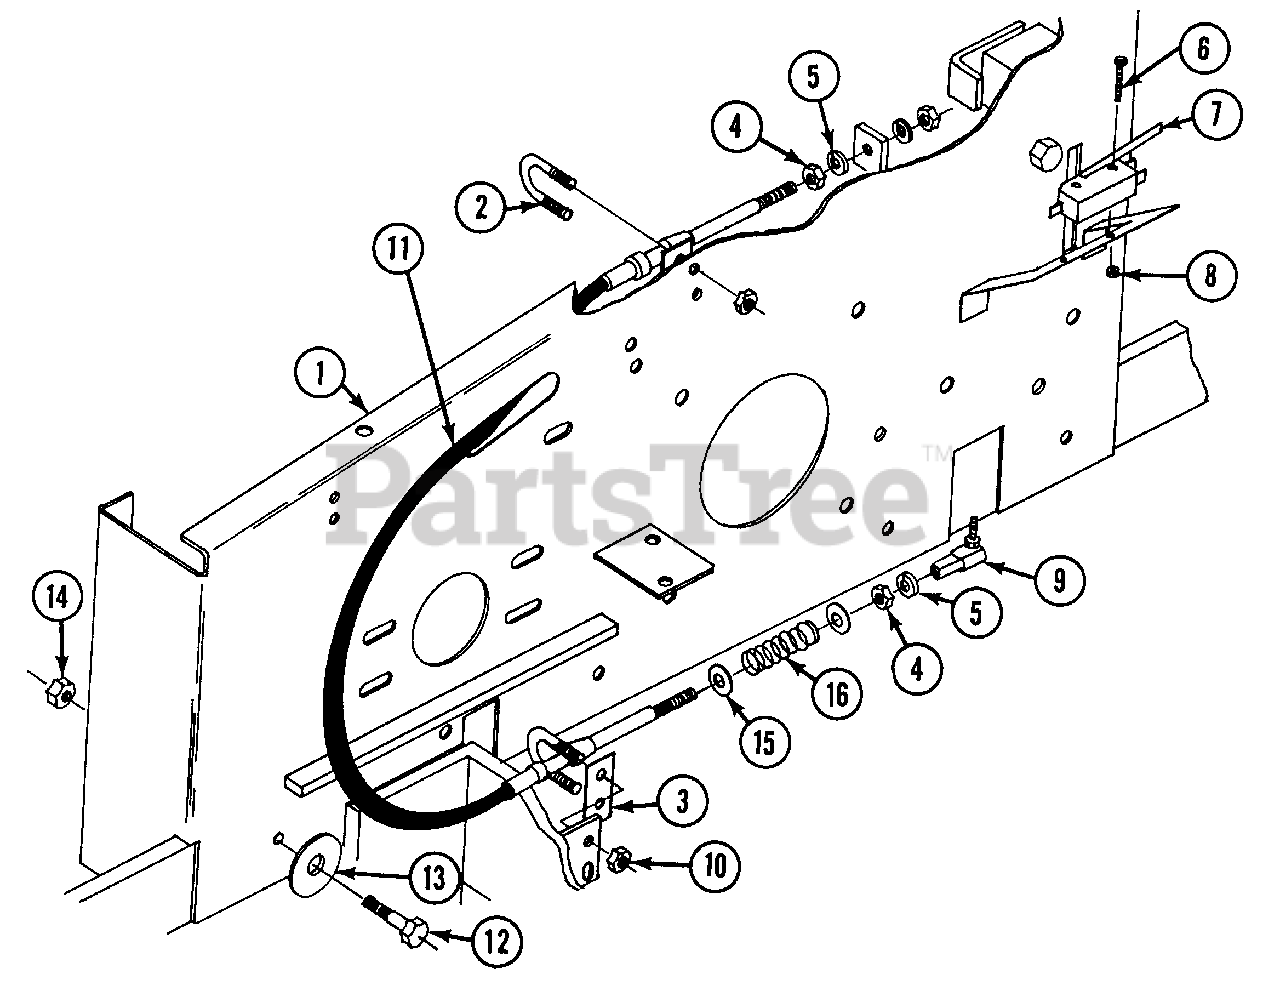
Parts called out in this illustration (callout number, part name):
1	SIDE PLATE WELDMENT LEFT ("S" FRAME)
1	SIDE PLATE WELDMENT LEFT ("LB" & "LK" FRAME)
1	SIDE PLATE WELDMENT RIGHT ("S" FRAME)
1	SIDE PLATE WELDMENT RIGHT ("LB" & "LK" FRAME)
2	U-BOLT, 5/16-18 X 1-3/16
3	U-BOLT SPACER
4	NUT, HEX, 1/4-28 (COMES WITH #11)
5	LOCKWASHER, 1/4 STD, SPLIT SPRING
6	SCREW, ROUND HEAD SLOTTED, 6-32 X 1
7	SWITCH, SINGLE POLE, 15A
8	LOCKNUT, HEX, 6-32, W/NYLOC
9	BALL JOINT, 1/4-28
10	LOCKNUT, HEX, 5/16 THIN HEIGHT, W/NYLOC
11	CABLE, PUSH/PULL, SERIES 40, 34" OAL
12	CAPSCREW, HEX, 3/8-24 X 1-1/4, GRADE 5
13	WASHER, .406 ID, 1.240 OD, .168 THK
14	LOCKNUT, 3/8-24
15	WASHER, 6.4 MM I.D. (ZINC PLATED)
16	COMPRESSION SPRING, .366 O.D. X 2.4 LG.
